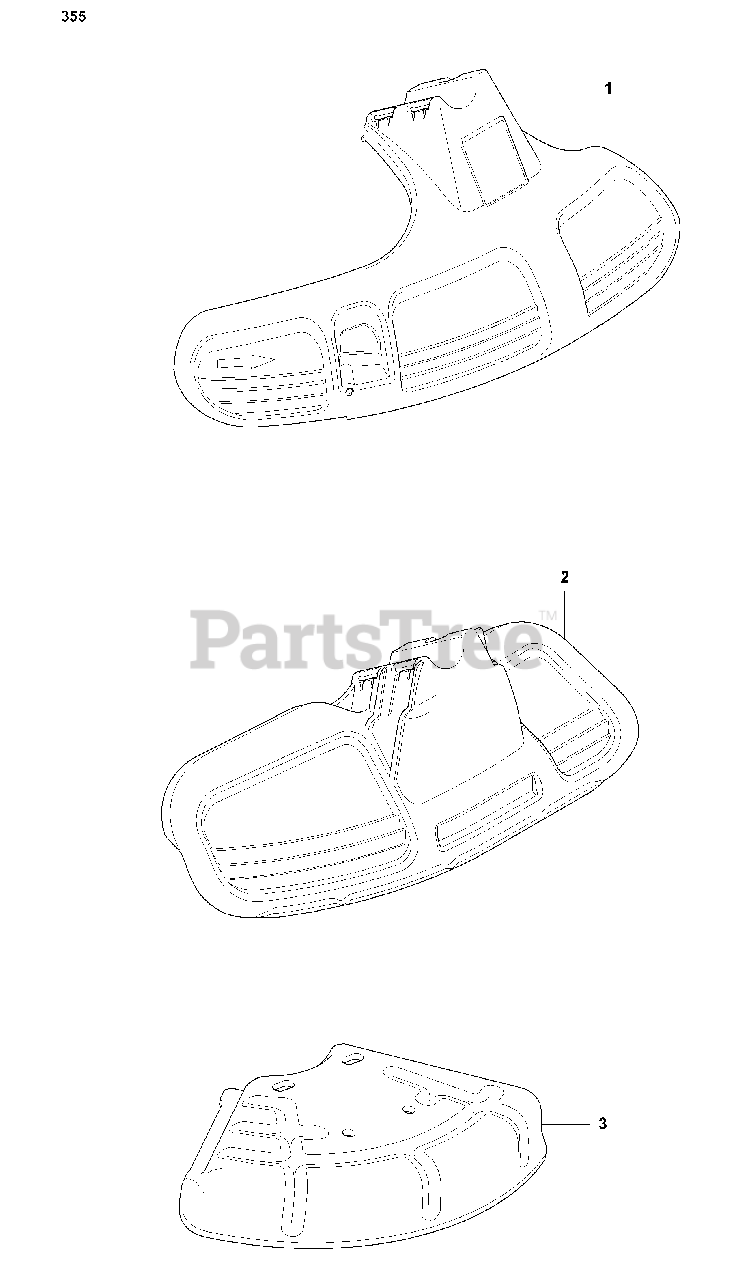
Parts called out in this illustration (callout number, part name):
1	PROTECTION
2	BLADE GUARD GRASS
3	BLADE GUARD SAW
